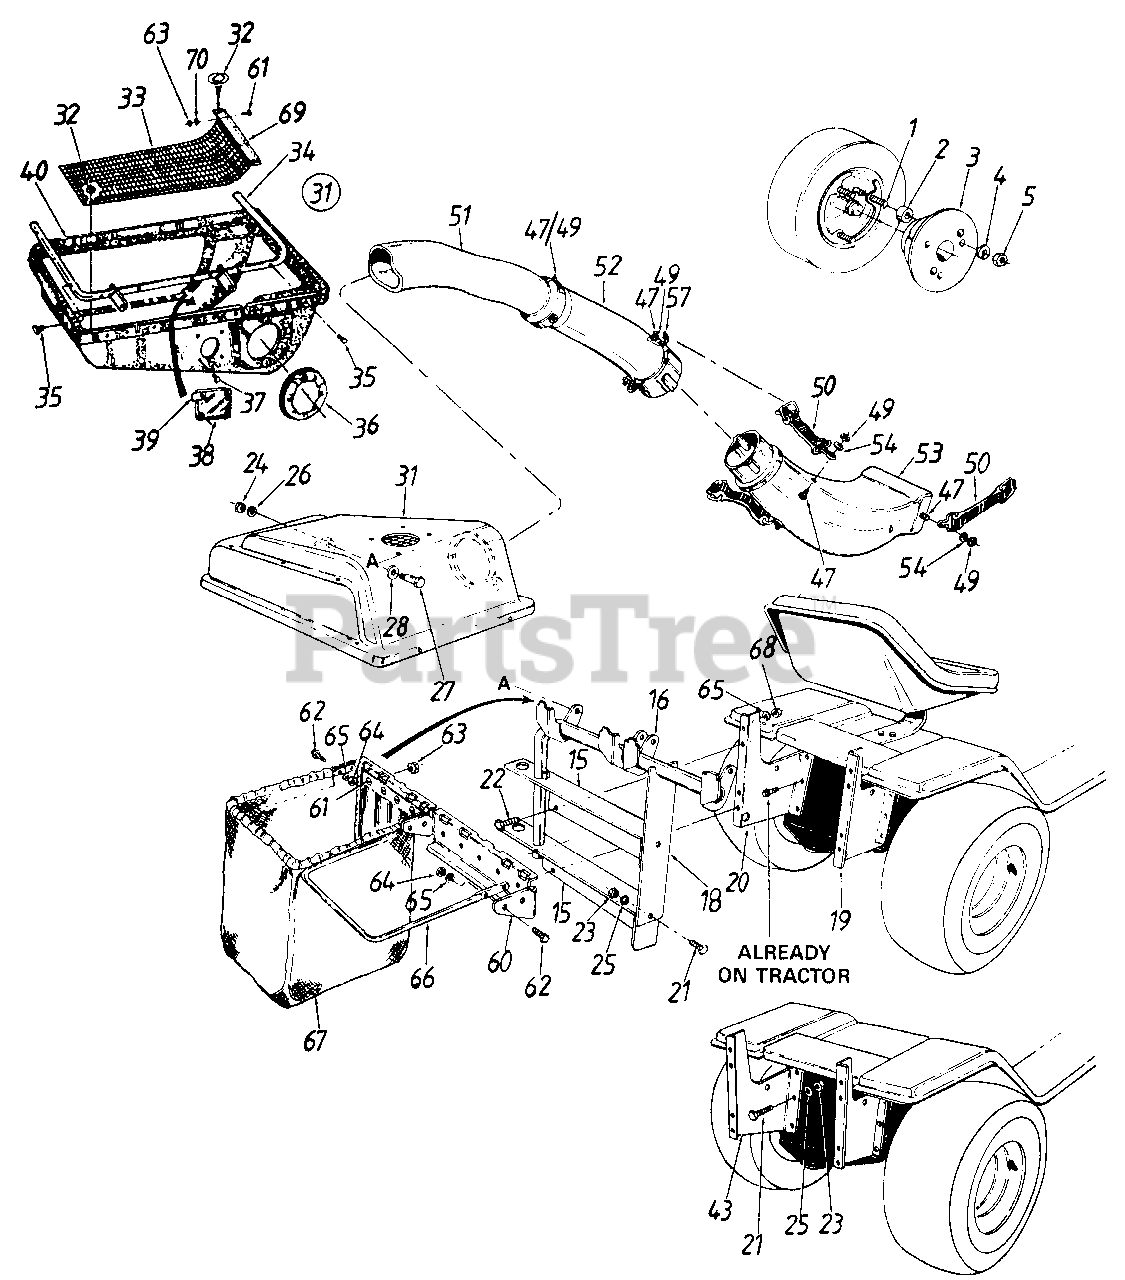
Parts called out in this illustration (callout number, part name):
1	Wheel Weight Snap Ring
2	Spacer
3	Wheel Weight
4	Lock Washer 5/16" I.D.
5	Hex Nut 5/16-18 Thread
15	Catcher Support Tube Mtg. Brkt.
16	Catcher Support Tube Assy.
18	Catcher Latch and Support Brkt.
19	Grass Catcher Support Brkt. R.H.
20	Grass Catcher Support Brkt. L.H.
21	Hex Bolt 5/16-18 x .75" Lg.
22	Hex Bolt 1/4-20 x .62" Lg. Grade 5
23	Hex Nut 5/16-18 Thd.
24	Hex Nut 3/8-16 Thd.
25	L.-Wash. 5/16" I.D.
26	L.-Wash. 3/8" I.D.
27	Shld. Bolt 3/8-16 x .500" Dia.
28	Bell.-Wash. .505" I.D. x 1.00" O.D.
31	Grass Catcher Cover Ass'y.
32	Twist Fastener
33	Screen
35	Hex Tap Scr. 1/4-20 x .5" Lg.
36	Seal
37	Truss Mach. B-Tap Scr. #10 x .5" Lg.
38	Plastic Plate
39	Speed Nut
40	Grass Catcher Cover
47	Hex Bolt 1/4-20 x .50" Lg.
49	Hex Ins. L.-Nut 1/4-20 Thd.
50	Retainer Strap Ass'y.
51	Catcher Elbow
52	Catcher Tube
53	Discharge Chute
54	L.-Wash. .27" I.D.
57	Retainer Hook Brkt.
61	Truss Mach. Scr. #10-24 x .50" Lg.
62	Hex Bolt 1/4-28 x .75" Lg.
63	Hex Sems Nut #10-24 Thd.
64	Hex Nut 1/4-28 Thd.
65	L.-Wash. 1/4" I.D.
67	Grass Catcher Bag
68	Hex Nut 1/4-20 Thd.
69	Screen Mtg. Brkt.
70	Flat Wash. 1/4" I.D.
